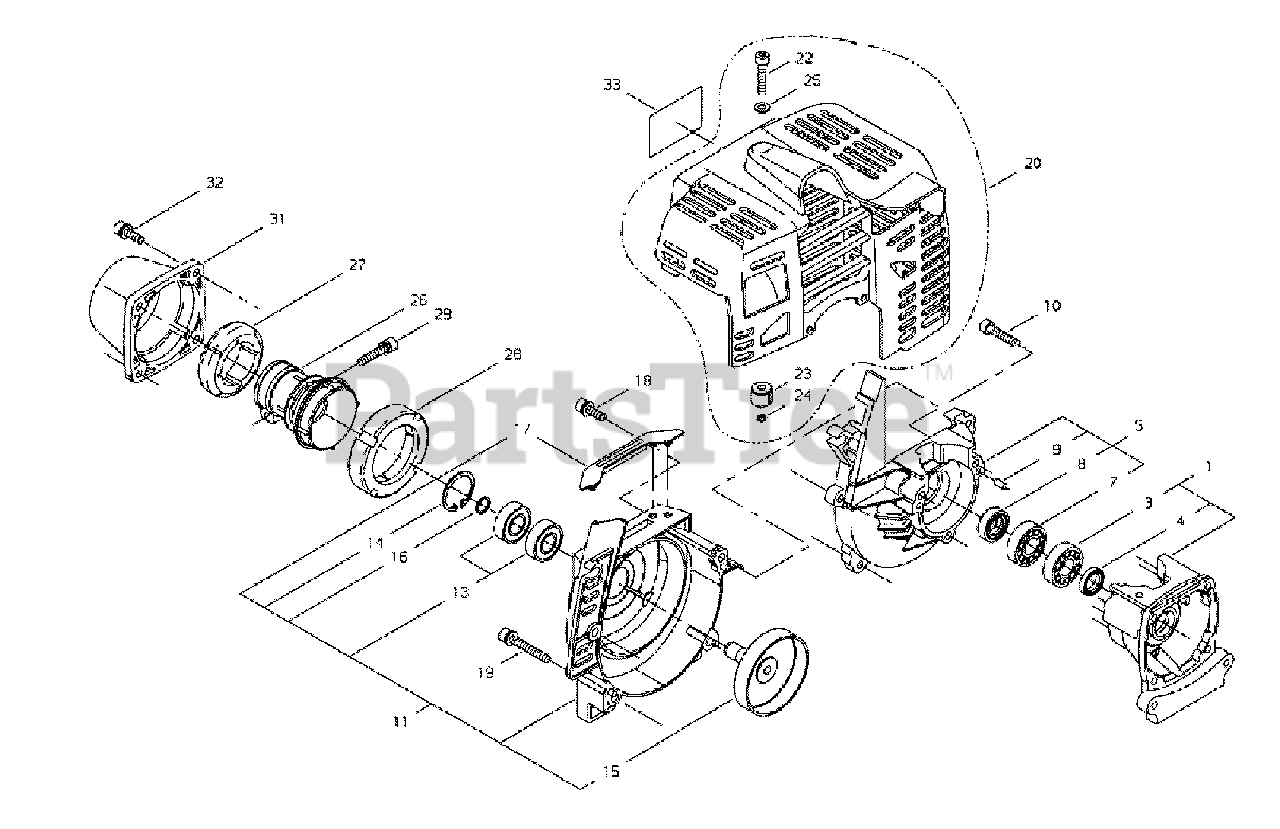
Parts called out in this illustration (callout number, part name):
1	CRANKCASE ASSY, S
3	BEARING, BALL 6001 C3
4	SEAL, OIL 12
5	CRANKCASE ASSY, M
7	BEARING, BALL 6001 C3
8	SEAL, OIL 12
9	PIN, LOCATING Ø4×8
10	BOLT 5×25
11	COVER ASSY, FAN
13	BEARING, BALL 6000ZZ
14	RING, SNAP Ø26
15	DRUM, CLUTCH
16	RING, SNAP WR10
17	CUSHION
18	BOLT M5×16
19	BOLT M5×45
20	COVER ASSY, ENGINE
22	BOLT 5×25
23	INSULATOR 5 MM
24	CLIP
25	WASHER 5 MM
26	JOINT
27	CUSHION, FRONT
28	HOLDER, REAR CUSHION
29	BOLT M5×25
31	COVER, AV CUSHION (RED)
32	BOLT M5×16
33	LABEL, AH231
